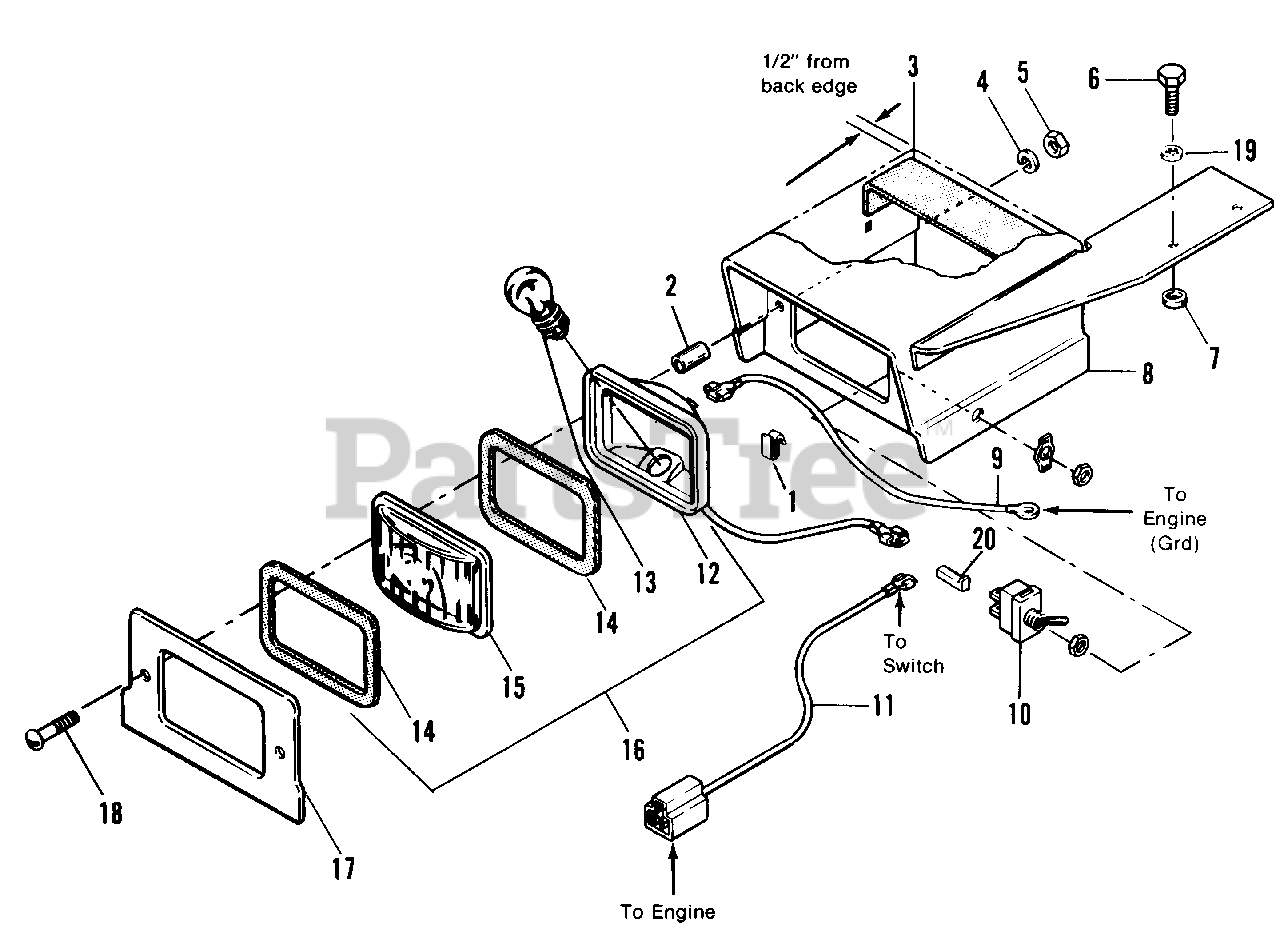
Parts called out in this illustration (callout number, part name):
1	CLIP, Wire (1691370, 1691371 only)
3	PAD, Rubber
4	LOCKWASHER, 1/4
5	NUT, Hex, 1/4-20
6	CAPSCREW, Hex Hd., 5/16-18 x 1
7	WASHER, Plain, 5/16 x 1 O.D.
8	COVER ASSY., Headlight
9	WIRE, Light to Ground
10	SWITCH, Toggle (Incl. washer & nuts)
11	WIRE, Engine to Switch (1691370, 1691371 only)
11	WIRE, Engine to Switch (1691716 only)
12	SOCKET, Reflector
13	BULB, #1141 (1691370, 1691371 only)
13	BULB, #1156 (1691716 only)
15	LENS, Amber
16	LIGHT ASSY. (Incl. Ref. Nos. 12 thru 15)
17	SUPPORT, Light
18	SCREW, Rd. Hd., 1/4-20 x 1
19	LOCKWASHER, Internal Tooth, 5/16
20	CONNECTOR BODY (1691716 only)
